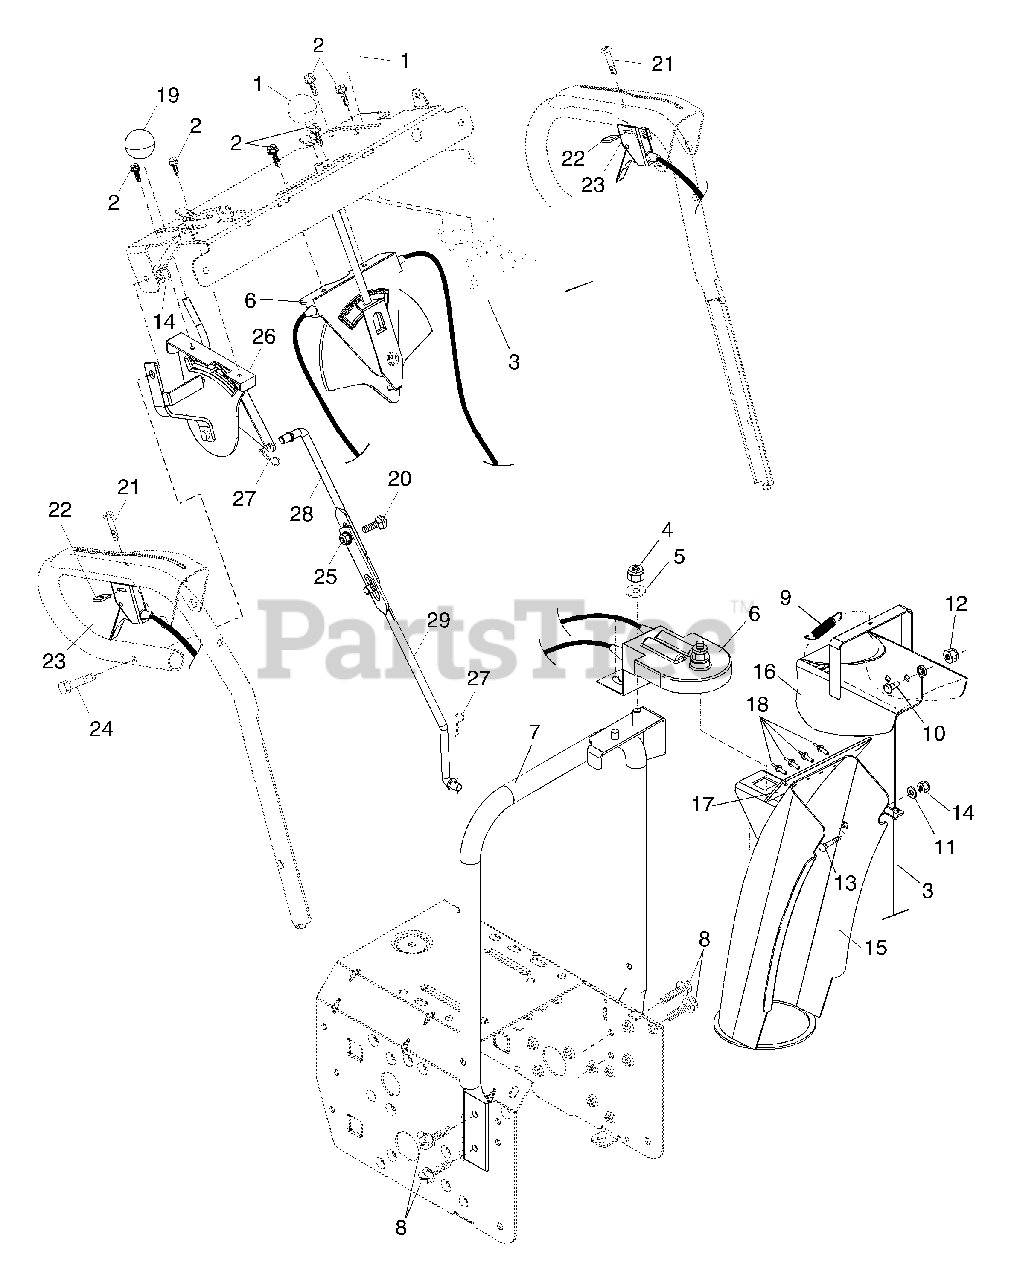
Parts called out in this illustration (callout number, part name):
1	Knob, Lever
2	Screw #10-24 x 5/8
3	Control Assembly, Deflector
4	Nut, Lock 3/8-16
5	Washer, Flat 3/8
6	Control Assembly, Chute Rotater
7	Support, Pivot
8	Screw, Hex Head 5/16-18 x 3/4
9	Spring, Deflector
10	Bolt, Shoulder
11	Washer, Flat
12	Nut, Lock 1/4-20
13	Bolt, Carriage 5/16-18
14	Nut, Lock 5/16-18
15	Chute Assembly
16	Deflector Assembly
17	Seal, Deflector
18	Rivet, Blind
19	Knob, Speed Control Lever
20	Bolt, Carriage 5/16-18 x 3/4
21	Screw #10-24 x 1-1/2
22	Nut, Weld #10-24
23	Control Assembly, Power Steering
24	Screw, Hex Head 5/16-18 x 1-3/4
25	Nut, Lock 5/16-18
26	Lever Assembly, Speed Control
27	Retainer, Hairpin
28	Rod, Upper, Speed Control
29	Rod, Lower, Speed Control
